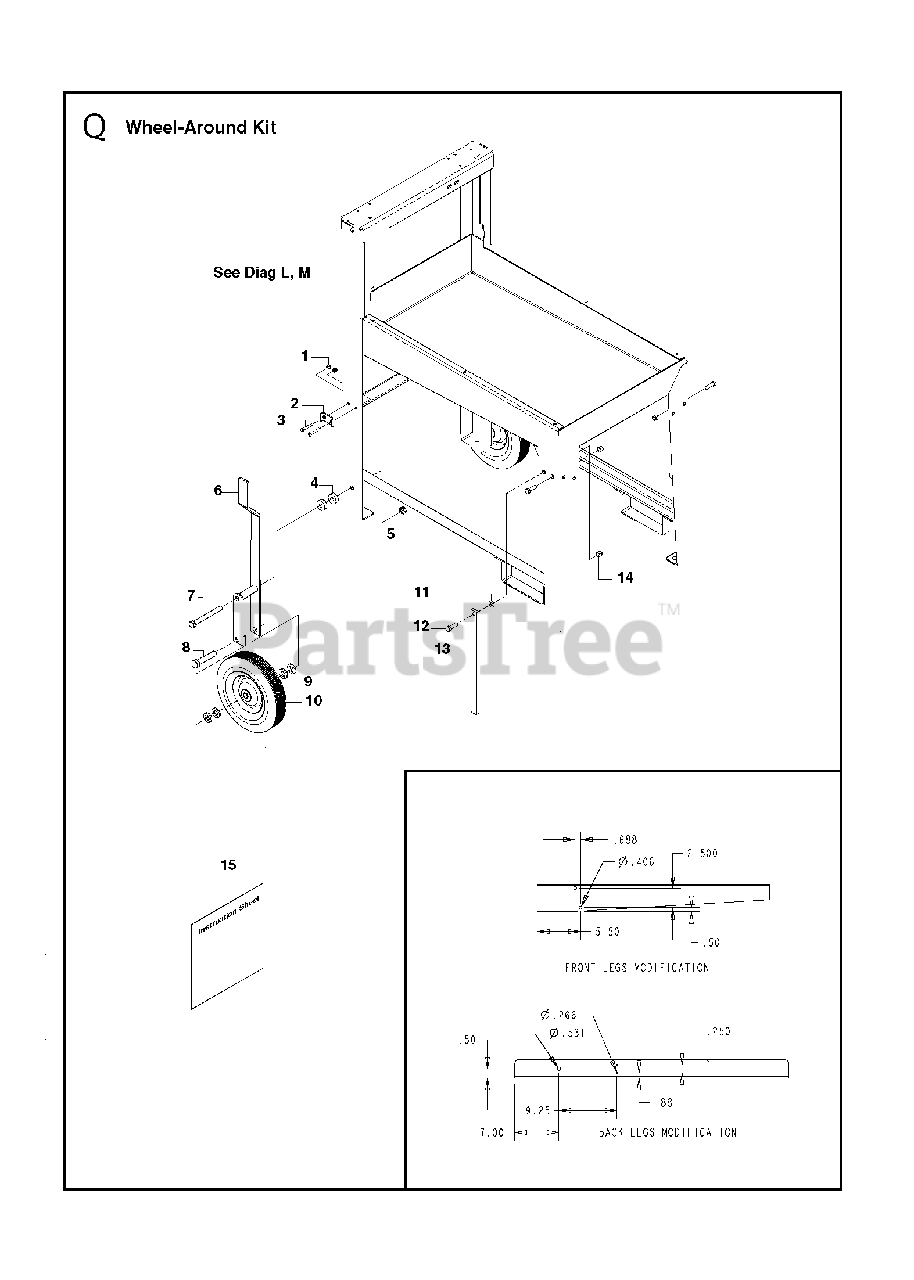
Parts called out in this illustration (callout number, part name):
1	NUT
5	NUT
11	WASHER
14	NUT
